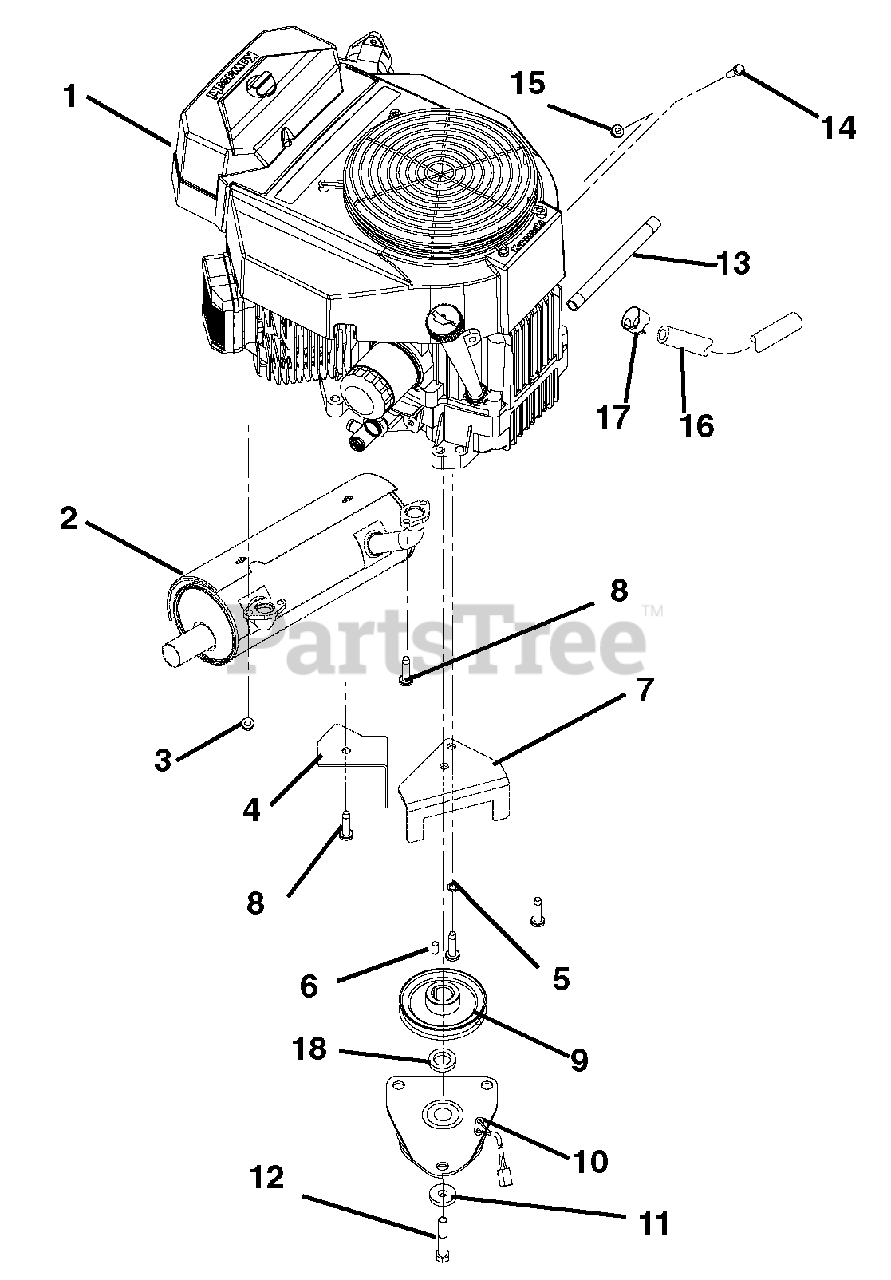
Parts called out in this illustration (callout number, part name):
1	ENGINE, KAWASAKI FR691 (24HP)
1	ENGINE, KAWASAKI FR730 (26HP)
2	MUFFLER, KAWASAKI FX 24/26HP
3	NUT-LK-TOP M8-1.25 YWZC
4	GUARD, HD CLUTCH WIRE
5	@WSHR-LK-EXT.391X.628X.036YWZC
6	KEY-SQ .25X.625X.25 SAE 8630
7	ANCHOR - OGURA CLUTCH - HD
8	BLT-HEX.38-16X1.25FTHG5 EP30YZ
9	PULLEY, 4.50 OD X 1.002 ENGINE
9	PULLEY,4.50"OD X 1.002" ENGINE
10	CLUTCH ASSY, OGURA# GT1A-HU02
10	CLUTCH, OGURA GT1A-MT08
11	WSHR-FL-STL .469X2.00X.25 YWZC
12	BLT-HEX .44-20X3.00 G5 YZ EP80
12	BLT-HEX .44-20X2.50 G5 YZ EP80
13	HOSE, HYD .38-11-0K M6N0-F6J0
14	@BLT-HEX .31-18X1.00 GR5 YWZC
15	@NUT-LK-NYL-FLG .31-18 YWZC
16	HOSE, .25 LOW-PERM BULK GAS
17	CLAMP, FUEL LINE
18	SPACER 1.002ID X 1.75 OD X.266
18	WSHR-FL-STL 1.005X1.750X.131
19	@BLT-HEX M8-1.25X20 YWZC
